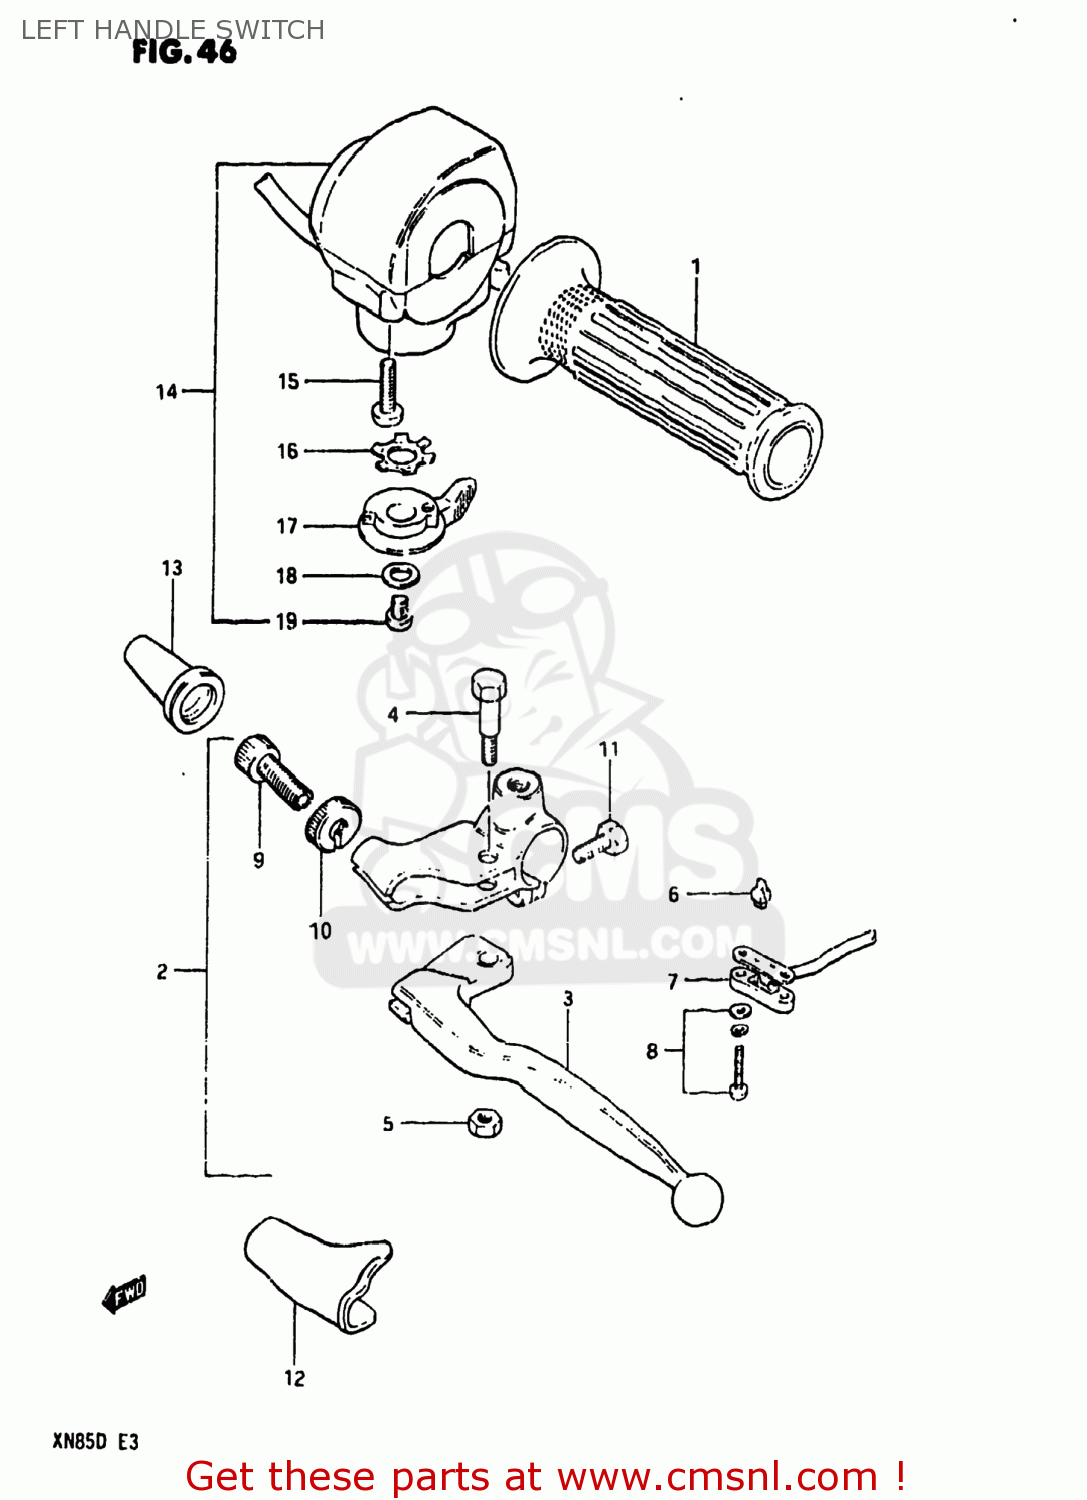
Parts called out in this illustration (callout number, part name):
1	GRIP,L
2	LEVER ASSEMBLY
3	LEVER,CLUTCH
4	BOLT,LEVER
5	NUT 6MM
6	CONTACT,SWITCH
7	COVER,FR BK TERMINAL BASE
8	SCREW
9	ADJUSTER,CABLE
10	NUT,CABLE ADJUSTER LOCK
11	BOLT,CLUTCH LEVER HOLDER
12	COVER,CLUTCH LEVER
13	BOOT,CLUTCH CABLE
14	SWITCH ASSEMBLY,HANDLE,LEFT
15	SCREW
16	WASHER
17	LEVER,CHOKE
18	WASHER 6MM
19	SCREW
